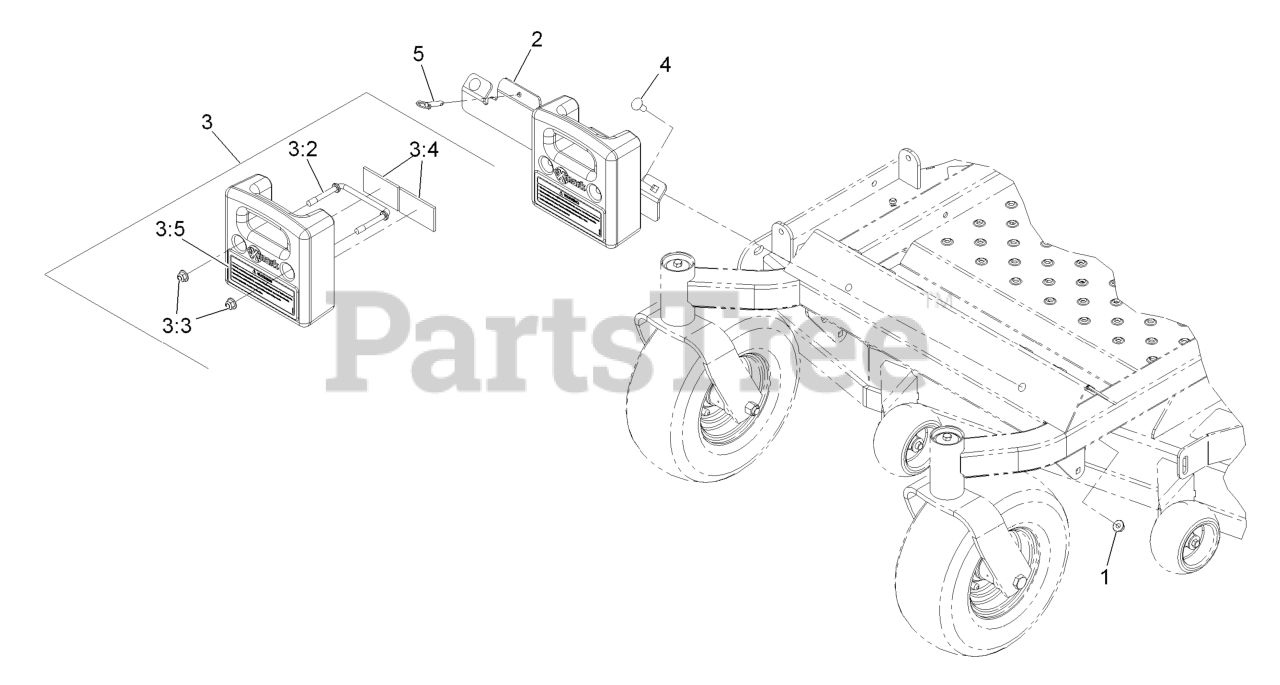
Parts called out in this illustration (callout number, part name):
1	NUT-HF, NI
2	BRACKET-WEIGHT MOUNT
3	WEIGHT ASM
3:2	WIREFORM-WEIGHT
3:3	NUT-HF, NI
3:4	CUSHION-RUBBER
3:5	DECAL,WEIGHT
4	BOLT-CARR
5	PIN-BALL, DETENT
